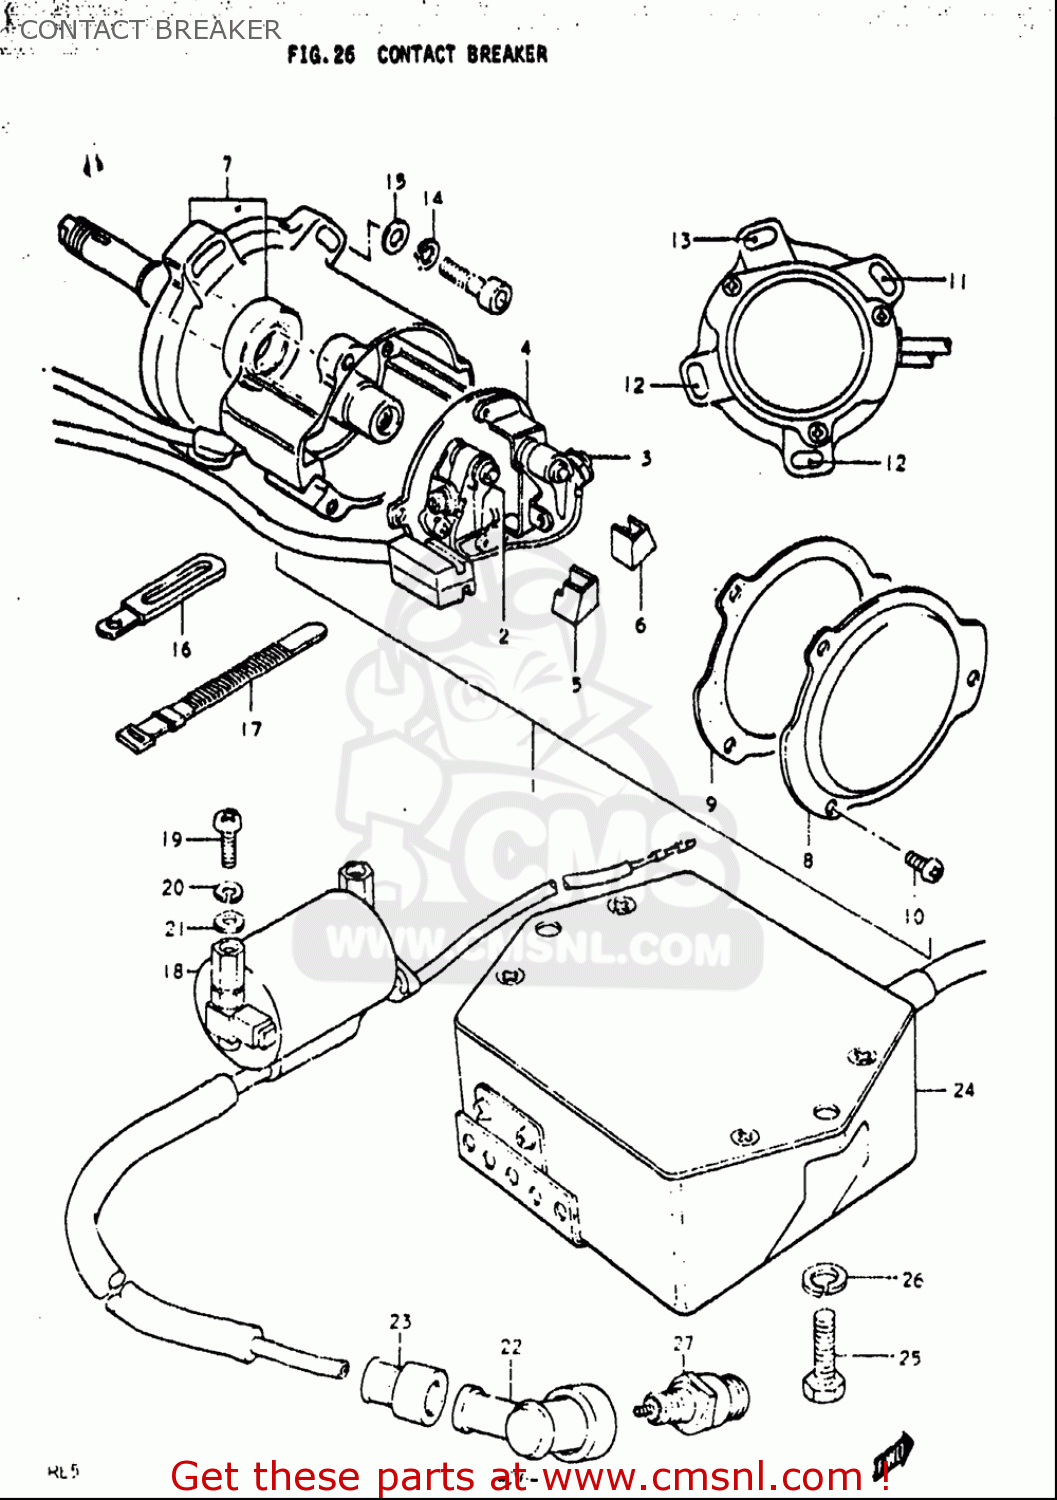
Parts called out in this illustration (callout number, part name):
10	SCREW
11	BOLT
14	WASHER,LOCK
15	WASHER
16	CLAMP(L:80 T:1.0)
17	CLAMP(L:120)
19	SCREW
20	WASHER,LOCK
21	WASHER
22	CAP,SPARK PLUG
23	SEAL,HIGH TENSION CORD
25	BOLT
26	WASHER,LOCK
27	PLUG,SPARK(AU10EFP)
